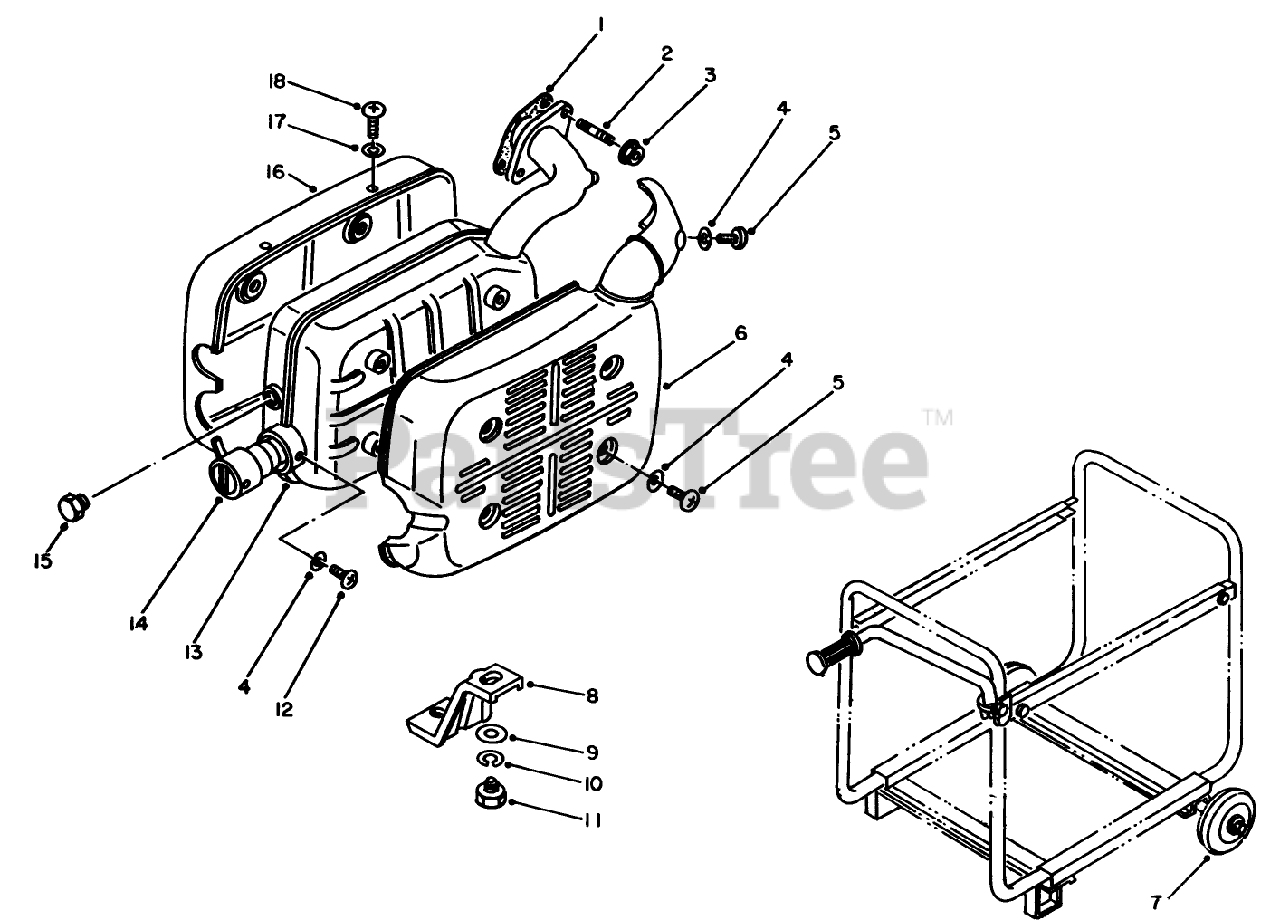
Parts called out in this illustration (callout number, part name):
5	SCREW
10	WASHER-LOCK
13	MUFFLER ASM
